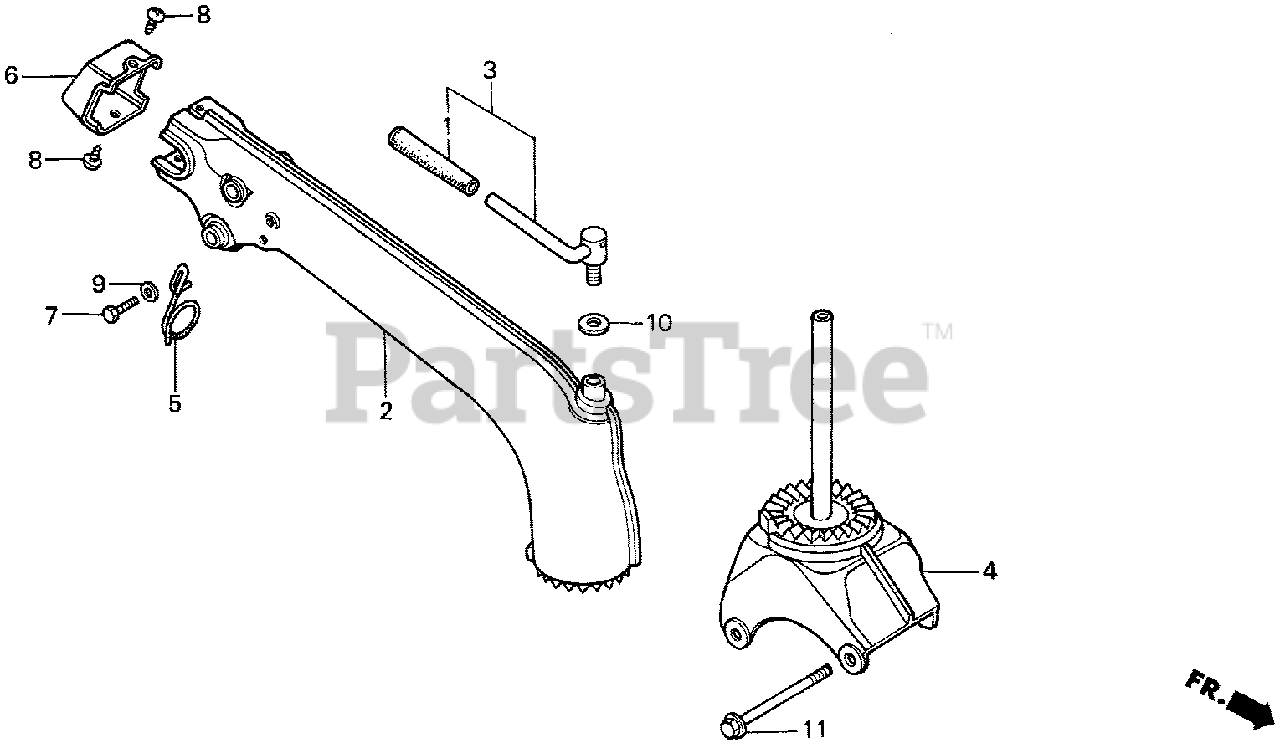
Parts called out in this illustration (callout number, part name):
1	GRIP, LEVER
2	COLUMN, HANDLE
3	LEVER, HANDLE ADJUSTING
4	BASE, SWING
5	GUIDE, CABLE
6	DASHBOARD, COLUMN *NH31* (MCKINLEY WHITE)
7	BOLT, HEX. (5X12)
8	SCREW, TAPPING (5X8) (NOT AVAILABLE)
9	WASHER, PLAIN (5MM)
10	WASHER, PLAIN (10MM)
11	BOLT, FLANGE (10X95)
